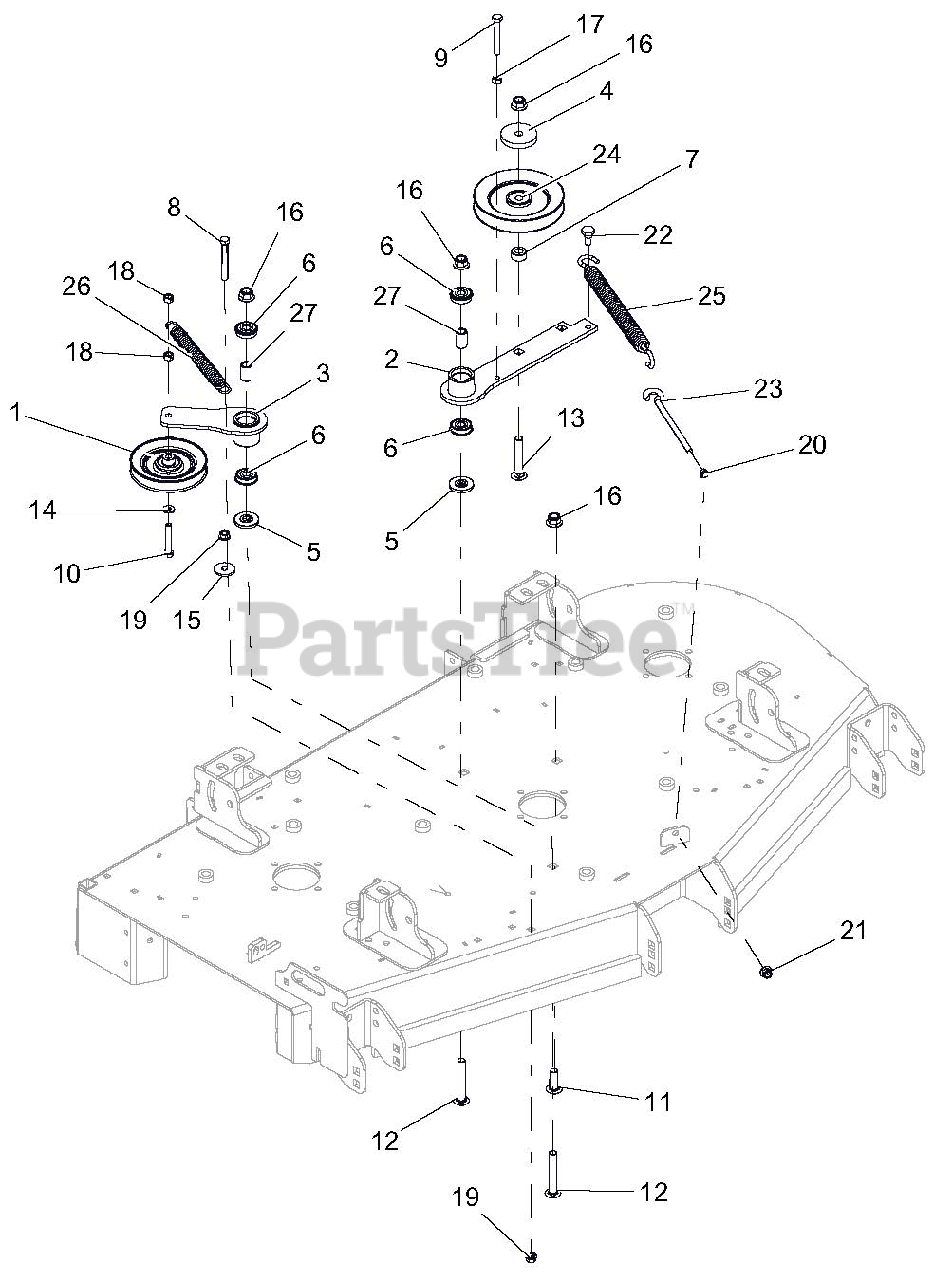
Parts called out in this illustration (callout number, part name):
1	IDLER, V-5.00" W/.69 STANDOFF
2	WLDMT, DECK PTO IDLER ARM
3	WLDMT, DECK RH IDLER ARM
4	CAP, IDLER BEARING SEALING
5	SPACER, IDLER ARM
6	BRG, BALL .501 X 1.38 X .438 SEALED
7	BSHG, SPCR .502 X .997.50 PM
8	BLT-HEX .38-16X3.00 GR5 YWZC
9	BLT-HEX .38-16X2.75 GR5 YWZC
10	BLT-HEX .38-16X2.25 GR5 YWZC
11	BLT-RDHDSQSHNK .50-13X1.50 YWZC
12	BLT-RDHDSQSHNK .50-13X3.25 YWZC
13	BLT-RDHDSQNK .50-13X3.00YG5
14	WSHR-FL-STL.406X.812X.065 YWZ
15	WSHR-FL-STL .406X1.375X.135 YZ
16	NUT-LK-NYL-FLG .50-13 YWZC
17	NUT-HEX .38-16 YWZC
18	NUT-LK-CTR .38-16 YWZC
19	@NUT-SPNLK-FLG .375-16 YWZC
20	NUT, JAM .375-16 YWZC
21	NUT-LK-NYL-FLG .38-16 YWZC
22	BLT, SHLDR EP .38-16X.30 HEX YZ
23	BOLT, .38-16X6.00 .62 DIA EYE
24	SHEAVE, .50" ID X 6.00" OD V-IDLER
25	SPRG, EXTENSION
26	SPRG, EXTENSION .120X.845X6.55 WLD
27	SPACER, .510 X .750 X 1.148
